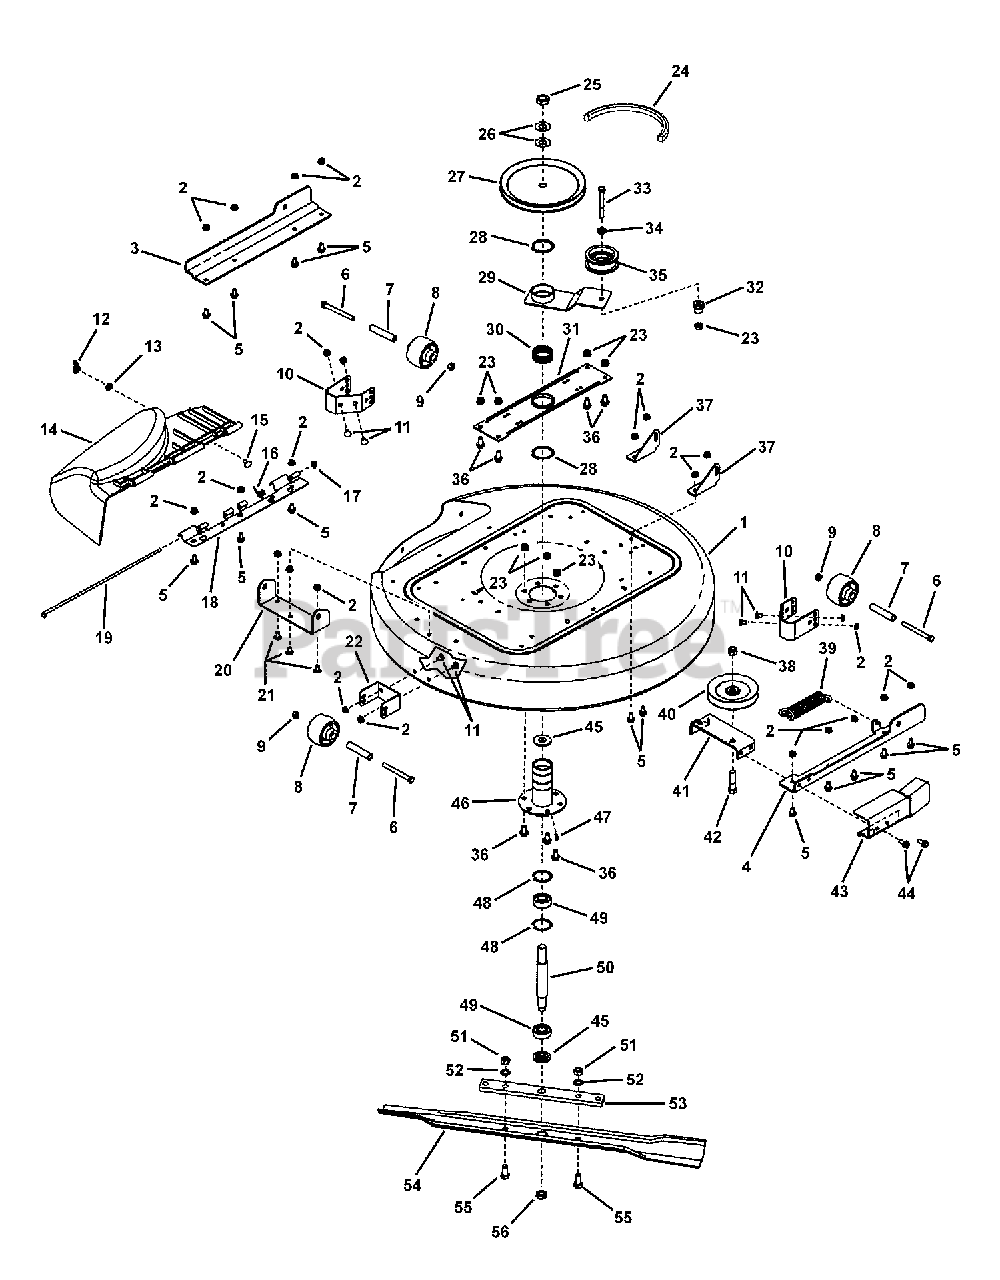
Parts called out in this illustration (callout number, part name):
1	DECK, 33" Mower
2	NUT, 5/16-18 Hex Flange Lock, GR5
3	RAIL, 33" Side - RH
4	RAIL, 33" Side - LH
5	BOLT, 5/16-18 x 5/8" Hex Flange Lock
6	SCREW, 3/8-24 x 3/4" Hex Head Cap, GR5
7	SPACER, 3" Long
8	WHEEL, Gage
9	NUT, 3/8-24 Hex Center Lock GR5 or B
10	BRACKET, Anti-Scalp Side Adjust
11	BOLT, 5/16-18 x 1/2" Round Head Short Square Neck, GR 5
12	WING NUT, 5/16-18, Type C, Style 1
13	WASHER, .34 x .69 x .08 Flat
14	DEFLECTOR, Discharge, 28"/33"
15	BOLT, 5/16-18 x 3/4" Round Head Short Square Neck, GR5
16	SPRING, Hinge
17	PUSH NUT, (for 1/4" Rod)
18	HINGE, Plastic Side Chute
19	ROD, Chute
20	BRACKET, Mower Front
21	BOLT, 5/16-18 x 5/8" Round Head Short Square Neck, GR5
22	BRACKET, Anti-Scalp Front Adjust
23	NUT, 3/8-16 Hex Flange Lock
24	* BELT, 33" Deck Drive (HB Section, 74.97 Effective Length)
25	NUT, 3/4-16 Hex Jam
26	WASHER, .77 x 1.5 x .06 Flat
27	PULLEY, 33" ZT Spindle
28	RETAINING RING, 2" External
29	WELDMENT, Idler Arm
30	TOLERANCE RING, 2.0
31	BRACE, Spindle
32	SPACER, .380/.377 I.D. x .750 O.D. x .970 Long
33	SCREW, 3/8-16 x 3-1/4" Hex Head Cap, GR5
34	WASHER, .375 Flat (.41 I.D. x .87 O.D.)
35	PULLEY, Idler, 2.75" x 3/8" ID
36	BOLT, 3/8-16 x 3/4" Hex Flange Lock, GR5
37	BRACKET, Deck Pick-Up
38	NUT, 1/2-13 Hex Nyloc Light
39	SPRING
40	PULLEY, Steel Idler
41	BRACKET, Pulley Mounting 33" ZT
42	SCREW,1/2-13 x 2" Hex Head Cap, GR5
43	GUARD, Idler Pulley, 33" ZT
44	SCREW, 5/16-18 x 3/4" Hex Washer Self-Tap
45	WASHER, Spindle
46	WELDMENT, Spindle Housing
47	LUBE FITTING, 3/16" Press-In
48	RING, 1.85" Internal Retaining
49	BEARING, Spindle
50	SHAFT, Spindle, 7.54" Long
51	NUT, 1/2-20 Hex
52	WASHER, 1/2" Internal Tooth Lock
53	HOLDER, Blade
54	BLADE, 33" High Lift
55	SCREW, 1/2-20 x 1-1/4" Hex Head Cap, GR5
56	NUT, 5/8-18 Hex Center Lock Jam
